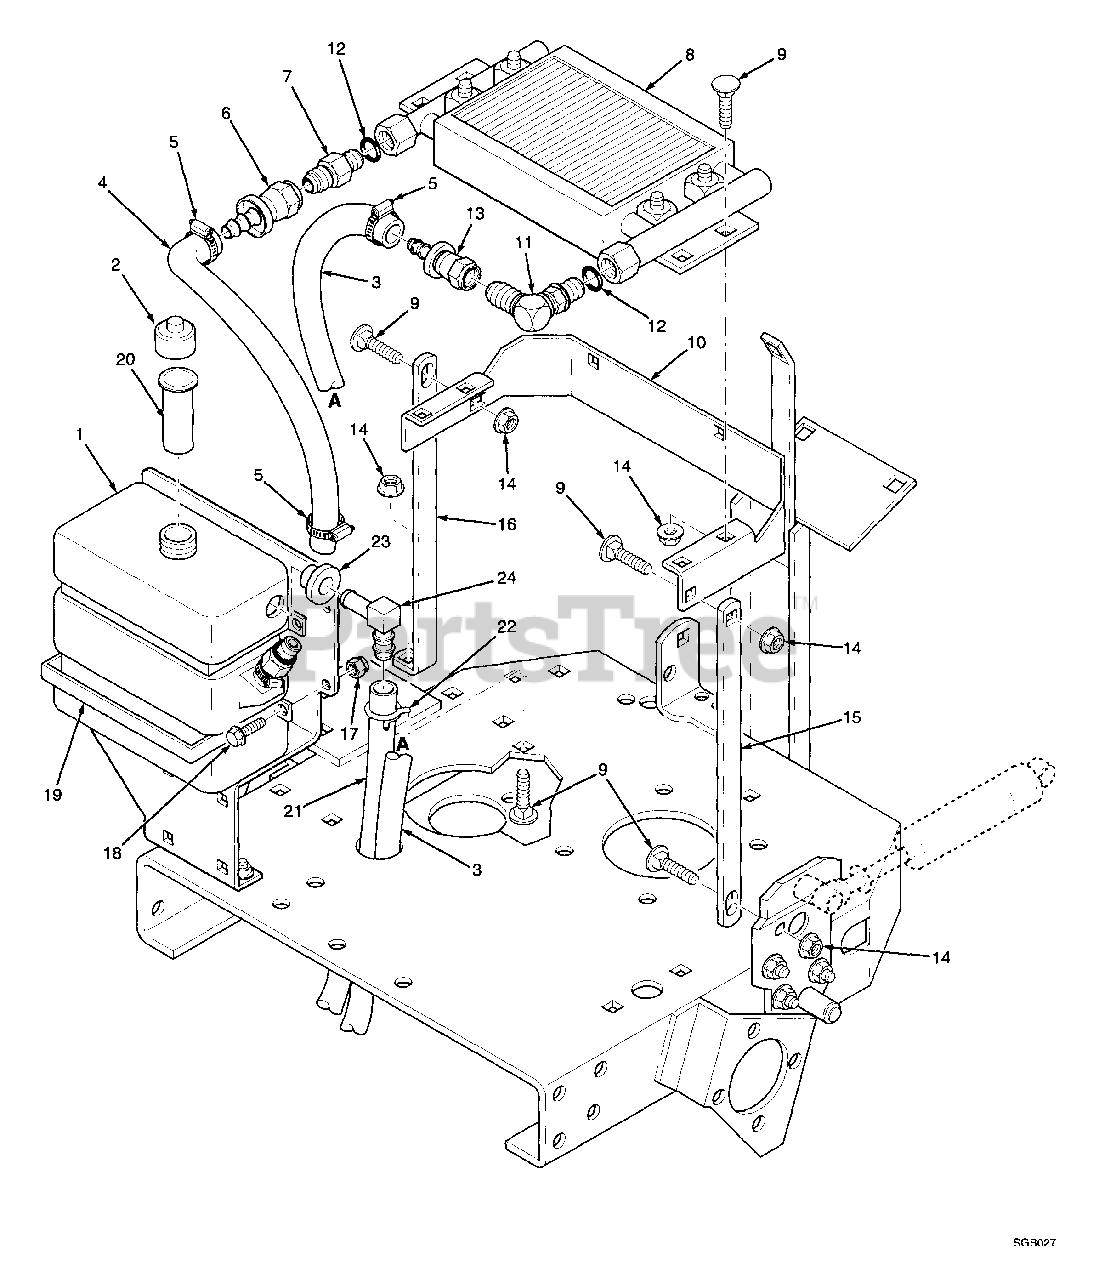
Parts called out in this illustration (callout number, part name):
1	Tank, Hydraulic
2	Cap, Hydraulic Tank
3	Hose, Pump to Oil Cooler
4	Hose, Oil Cooler to Tank
5	Clamp, Hose
6	Coupling, Flare Swivel
7	Tube, Union
8	Oil Cooler Assembly
9	Carriage Bolt, 5/16-18 x 3/4
10	Bracket, Oil Cooler
11	Elbow, 90 Degrees
12	O-Ring
13	Coupling Flare Swivel
14	Serr Fl Hex Head Nut, 5/16-18
15	Brace, L.H Cooler Support
16	Brace, R.H. Cooler Support
17	Elastic Stop Nut, 1/4-20
18	Serr. Fl. Hex Head CPSCR, 1/4-20 x 3/4
19	Strap, Oil Tank
20	Filler Neck Insert
21	Hose, 1/4" Pushlock x 27"
23	Bushing
24	90 Degree Elbow
